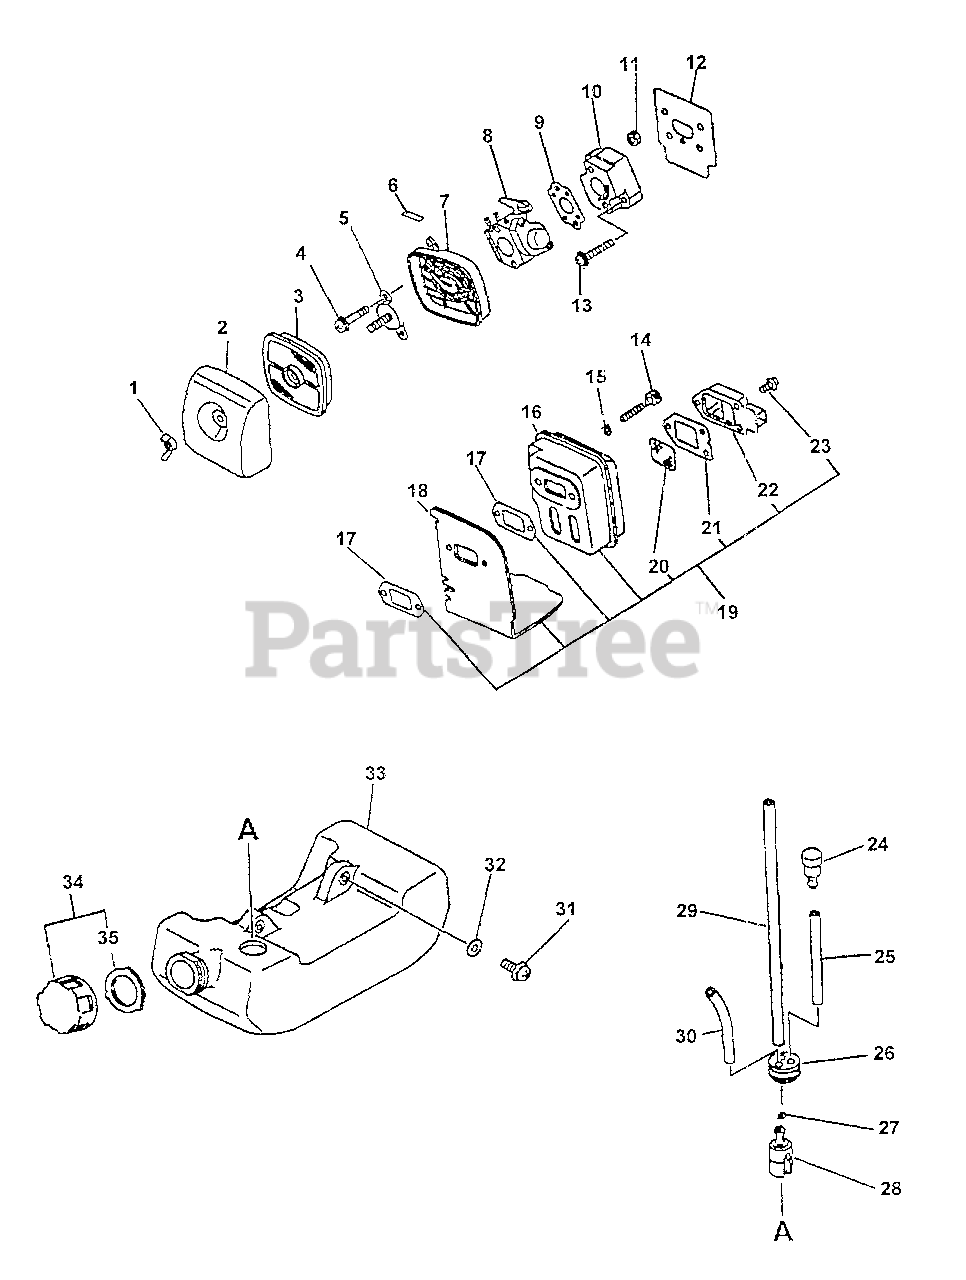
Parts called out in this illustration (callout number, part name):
1	WINGNUT - 6
2	COVER, AIR FILTER
3	FILTER, AIR - SINGLE LAYER
4	SCREW - 5X65
5	PLATE, PREVENT
6	LABEL - CHOKE
7	AIR FILTER CASE ASSY
8	CARBURETOR C1U-K29
9	GASKET, INTAKE
10	INSULATOR, INTAKE
12	SHIELD, INTAKE
13	SCREW - 5X20
14	SCREW - 5X55
15	WASHER - 5
16	MUFFLER ASSY
17	GASKET, EXHAUST
18	COVER, EXHAUST
19	MUFFLER ASSY
20	SCREEN, SPARK ARRESTOR
21	GASKET, EXHAUST
22	GUIDE, EXHAUST - OUTER
23	SCREW - 4X10
24	VENT, FUEL TANK
25	PIPE - 3X5X70 -- BLACK
26	GROMMET
27	CLIP - 6
28	FILTER, FUEL
29	PIPE - 3X5X180 -- BLACK
30	PIPE - 3X6X80 -- CLEAR
31	SCREW - 5X16
32	WASHER - 5
33	TANK, FUEL
34	CAP ASSY
35	GASKET, CAP
